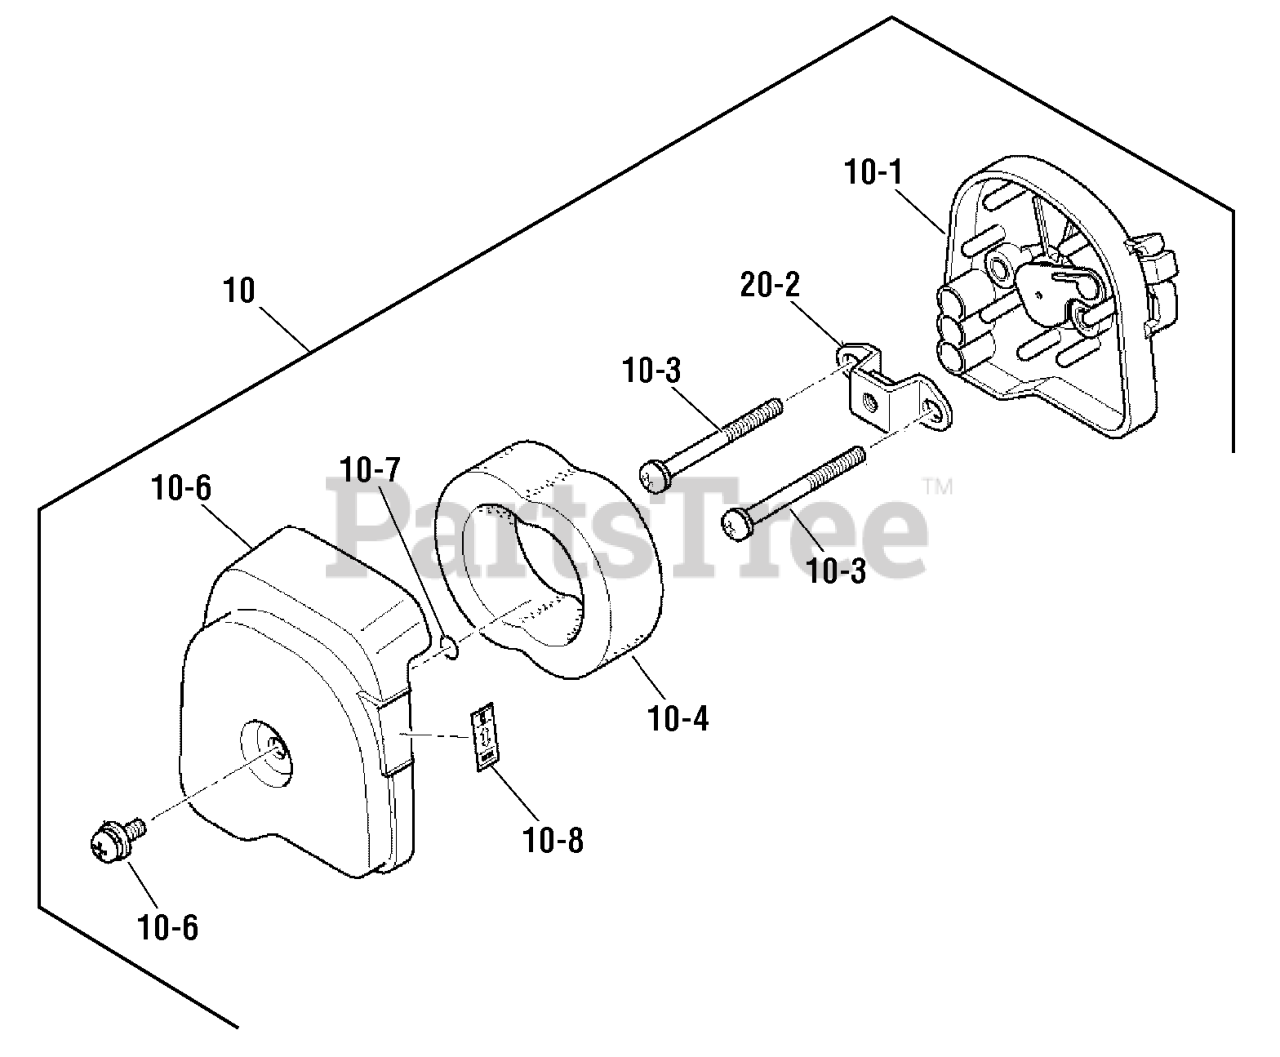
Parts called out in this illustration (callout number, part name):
10	AIR CLEANER ASSEMBLY
10-1	CASE, Cleaner
10-2	BRACKET
10-3	SCREW & WASHER
10-4	ELEMENT, Cleaner
10-5	COVER, Cleaner
10-6	SCREW & WASHER
10-7	O-RING
10-8	LABEL
